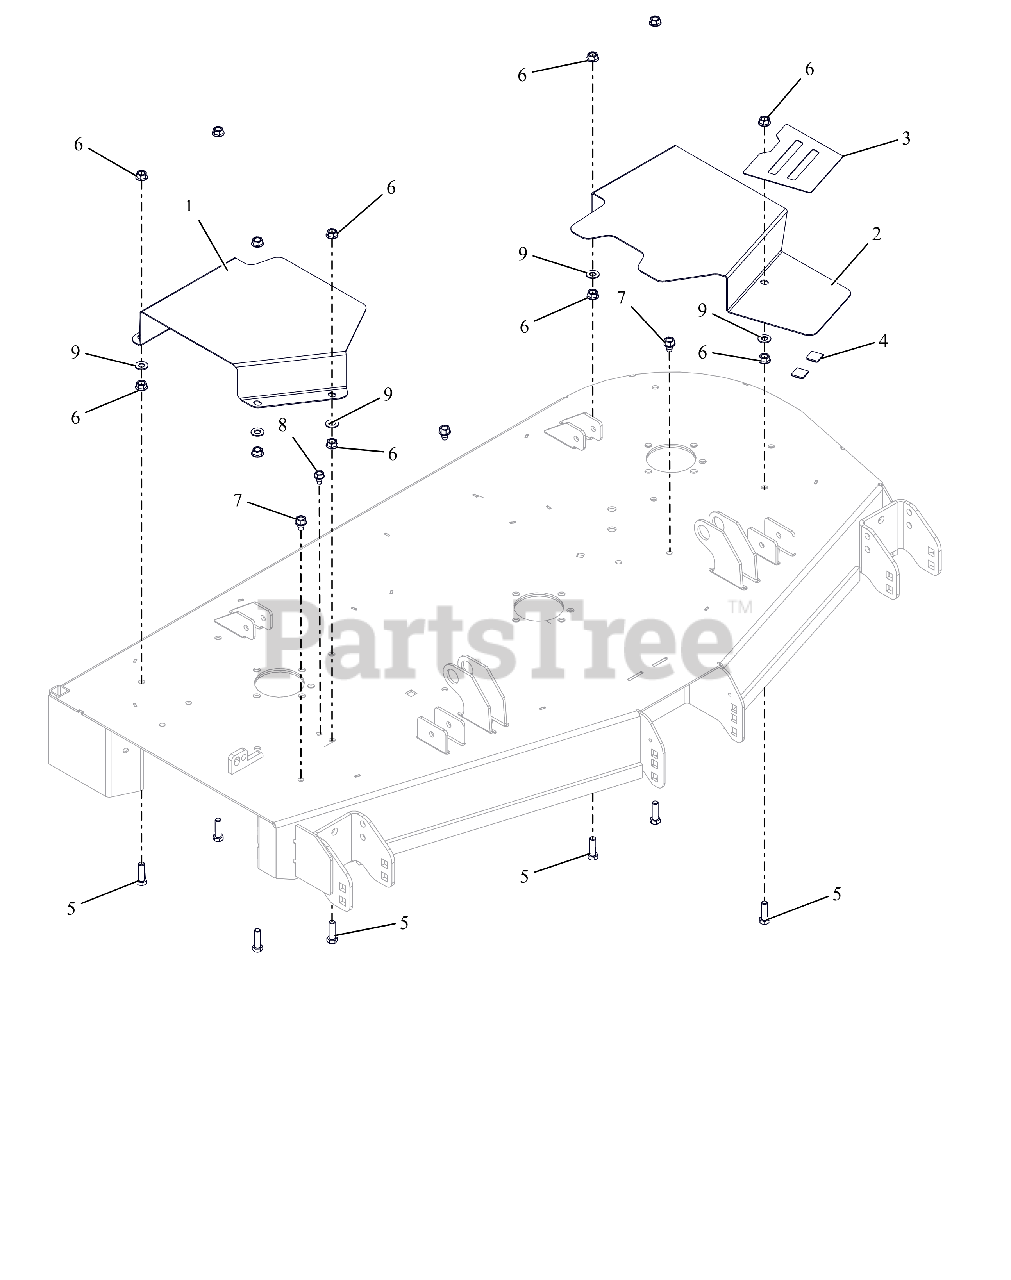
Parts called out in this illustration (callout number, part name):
1	COVER, BELT 52" & 60" RIGHT
2	COVER, BELT 52" LEFT
3	GRIP TAPE 52-60 BELT COVER
5	@BLT-HEX .38-16X1.25 GR5 YWZC
6	@NUT-SPNLK-FLG .375-16 YWZC
7	@SCR-TAP .38-16X.50 HWH TR YWZ
8	@SCR-TAP .31-18X.50 HWH TR YWZ
9	@WSHR-FL-STL.406X.812X.065 YWZ
